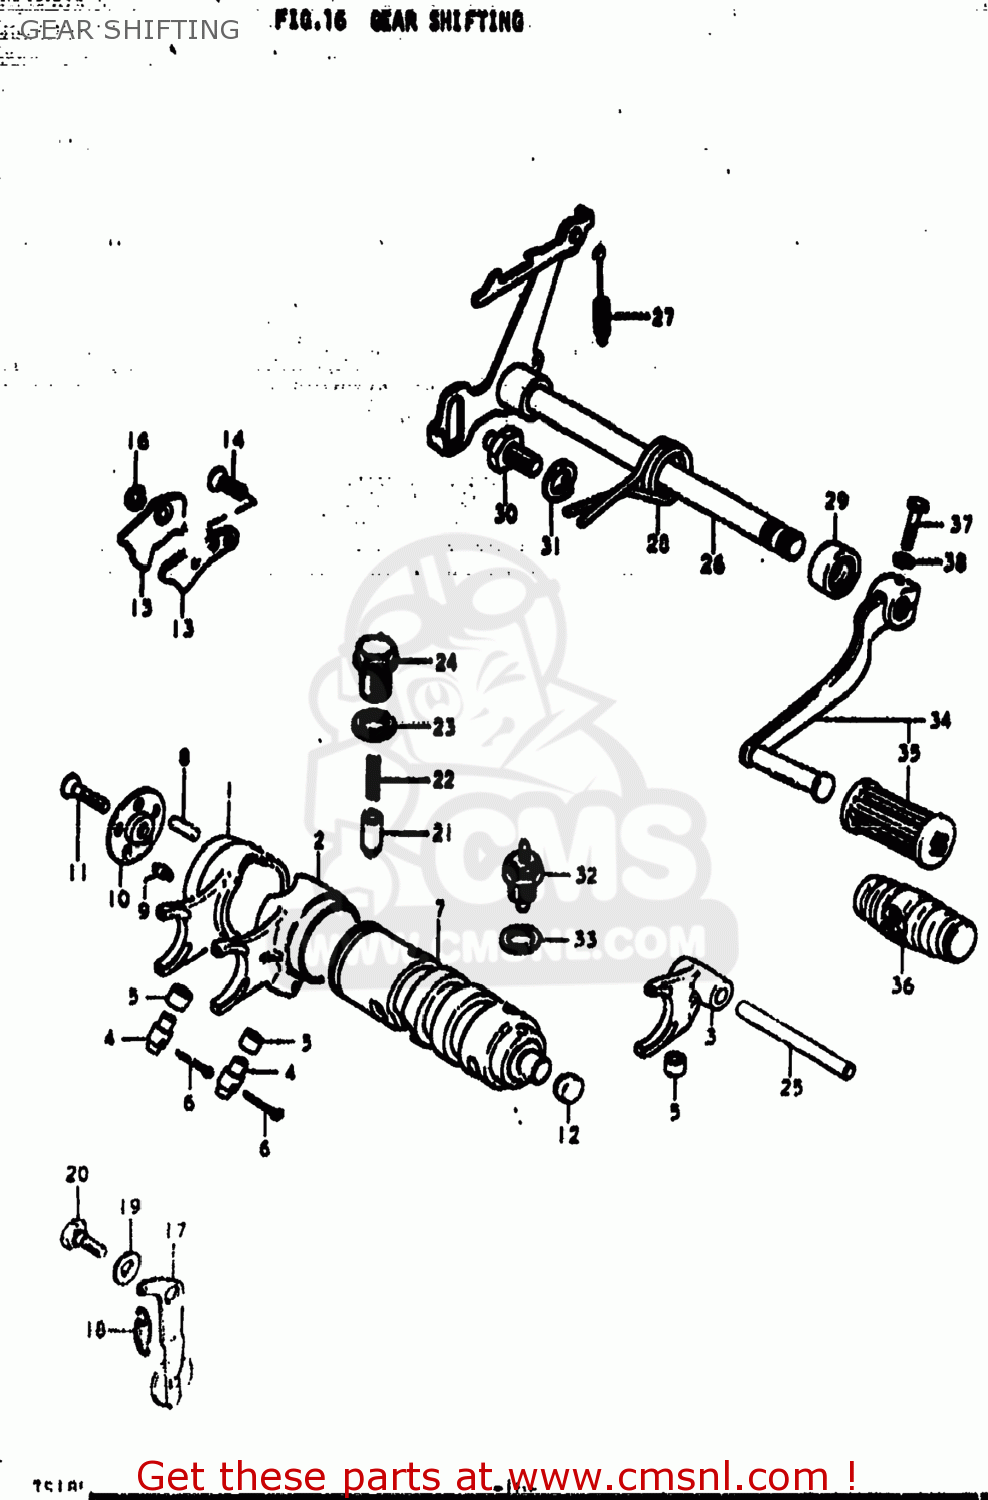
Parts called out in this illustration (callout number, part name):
1	FORK,GEAR SHIFT NO.1
2	FORK,GEAR SHIFT NO.2
3	FORK,GEAR SHIFT NO.3
4	PIN
5	SPACER
6	PIN 25X20
7	CAM,GEAR SHIFT
8	ROLLER(4X13.8)
9	PIN
10	RETAINER,GEAR SHIFT CAM DR PIN
11	SCREW
12	PLUG
13	GUIDE,GEAR SHIFT CAM
14	SCREW
15	PAWL,GEAR SHIFT CAM STOPPER
16	E RING
17	STOPPER,GEAR SHIFT CAM
18	SPRING
19	WASHER(6.5X16X2.3)
20	BOLT(6X16.1)
21	STOPPER,GEAR SHIFTING
22	SPRING
23	GASKET(14X19.2X2) (NAS)
24	BOLT,GEAR SHAFT CAM STOPPER
25	SHAFT,GEAR SHIFT FORK
26	SHAFT,GEAR SHIFT
27	SPRING
28	SPRING
29	SEAL,OIL(12X19X5)
30	STOPPER,GEAR SHIFT ARM
31	LOCK WASHER
32	SWITCH ASSEMBLY,NEUTRAL INDICATOR
33	GASKET(12.5X20X1) (NAS)
34	LEVER ASSY,GEAR SHIFT
35	RUBBER,GEAR SHIFT PEDAL
36	RUBBER,GEAR SHIFT PEDAL
37	BOLT
38	LOCK WASHER
